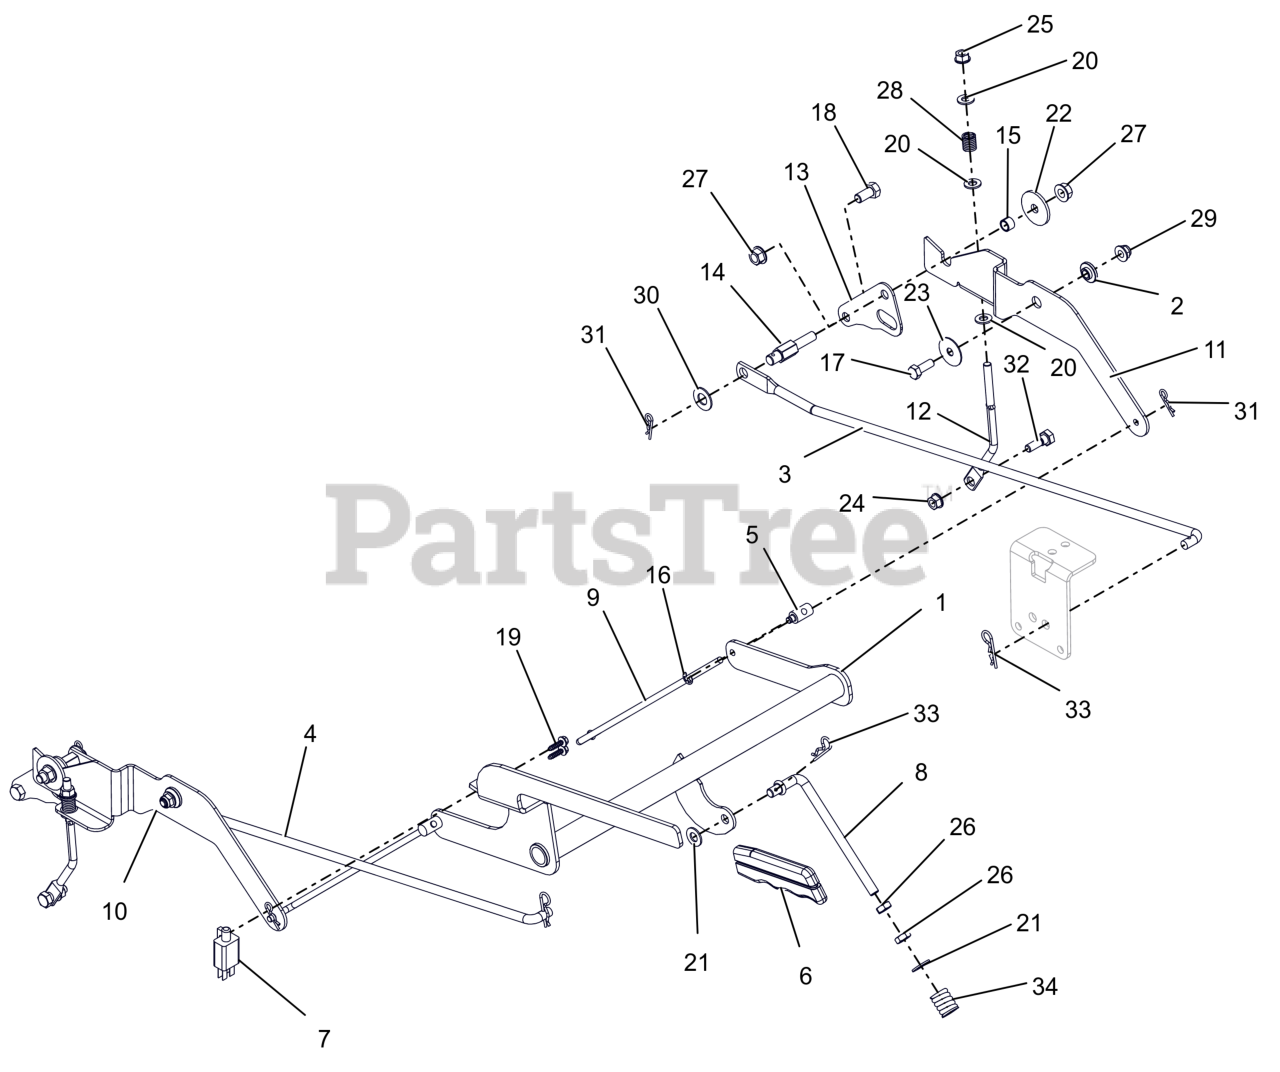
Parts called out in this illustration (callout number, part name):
1	WLDMT, BRAKE LEVER
2	BSHG, FLG .325X.499X.26X.88
3	LINKAGE, STEERING - LH
4	LINKAGE, STEERING - RH
5	TRUNION, 1/4-20
6	GRIP, PARKING BRAKE (YELLOW)
7	SWITCH- DOUBLE POLE N.O./N.O.
8	LINK, OVER CENTER, PARKING BRK
9	LINK, BRAKE ARM
10	INTERLOCK, RH BRAKE LINK
11	INTERLOCK, LH BRAKE LINK
12	LINK, BRAKE (XL)
13	PLATE, TRANSAXLE ADAPTOR
14	POST, STEERING LINK MOUNTING
15	SPCR, SLV .385X.500X.350
16	RG-RTNG-EXT .250X.025
17	BLT, HEX .31-18X.875 G5 ZCC
18	BLT,HEX .38-16X.75 G5 ZCC
19	SCR, PLASTITE #12X.75 ZCC
20	WSHR,FLT .344X.688X.065 ZCC
21	WSHR,FLT .406X.812X.065 ZCC
22	WSHR, FLT .380X1.50X.125 ZCC
23	WSHR, FLT .347X1.254X.048 ZCC
24	NUT-LK-TOP-FLG .312-18 GF ZCC
25	NUT,LK-CTR-FLG .31-18 GF ZCC
26	NUT-JAM .375-16 G2 ZCC
27	NUT-LK-CTR-FLG .375-16 GF ZCC
28	SPRING, COMPRESSION
29	NUT,LK-NYL-FLG .31-18 G5ZC120
30	WSHR, FLT .505X1.00X.062 ZCC
31	PIN, HAIR #213 .08X1.19 ZCC
32	BOLT,SHLDR .38X.25 -.31-18X.75
33	PIN, HAIR #203 .09X1.50 ZCC
34	SG-COMP .187X.56X1.62
